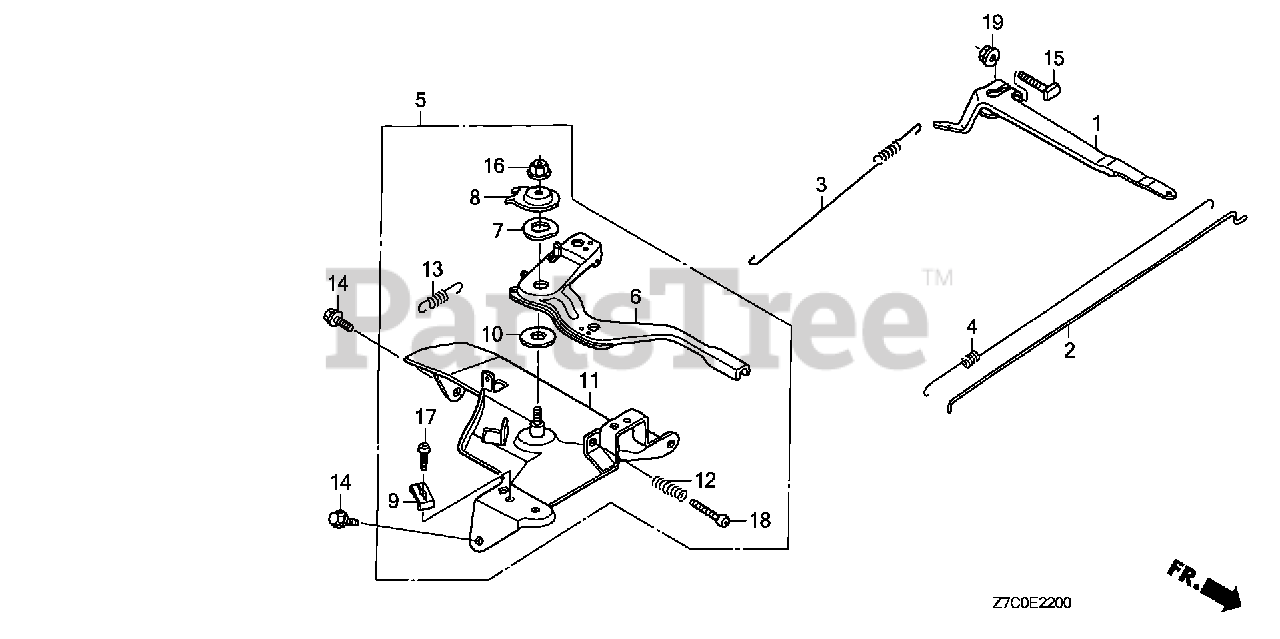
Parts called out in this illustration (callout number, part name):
1	ARM, GOVERNOR
2	ROD, GOVERNOR
3	SPRING, GOVERNOR (L=145.0MM) (WIRE DIAMETER 1.0MM)
4	SPRING, THROTTLE RETURN
5	CONTROL ASSY. (REMOTE)
6	LEVER, CONTROL
7	SPRING, LEVER
8	WASHER, CONTROL LEVER
9	HOLDER, CABLE
10	SPACER, CONTROL LEVER
11	BASE, CONTROL
12	SPRING, CONTROL ADJUSTING
13	SPRING, CABLE RETURN
14	BOLT, FLANGE (6X12) (CT200)
15	BOLT, GOVERNOR ARM
16	NUT, SELF-LOCK (6MM)
17	SCREW, PAN (5X16)
18	SCREW, PAN (5X28)
19	NUT, FLANGE (6MM)
